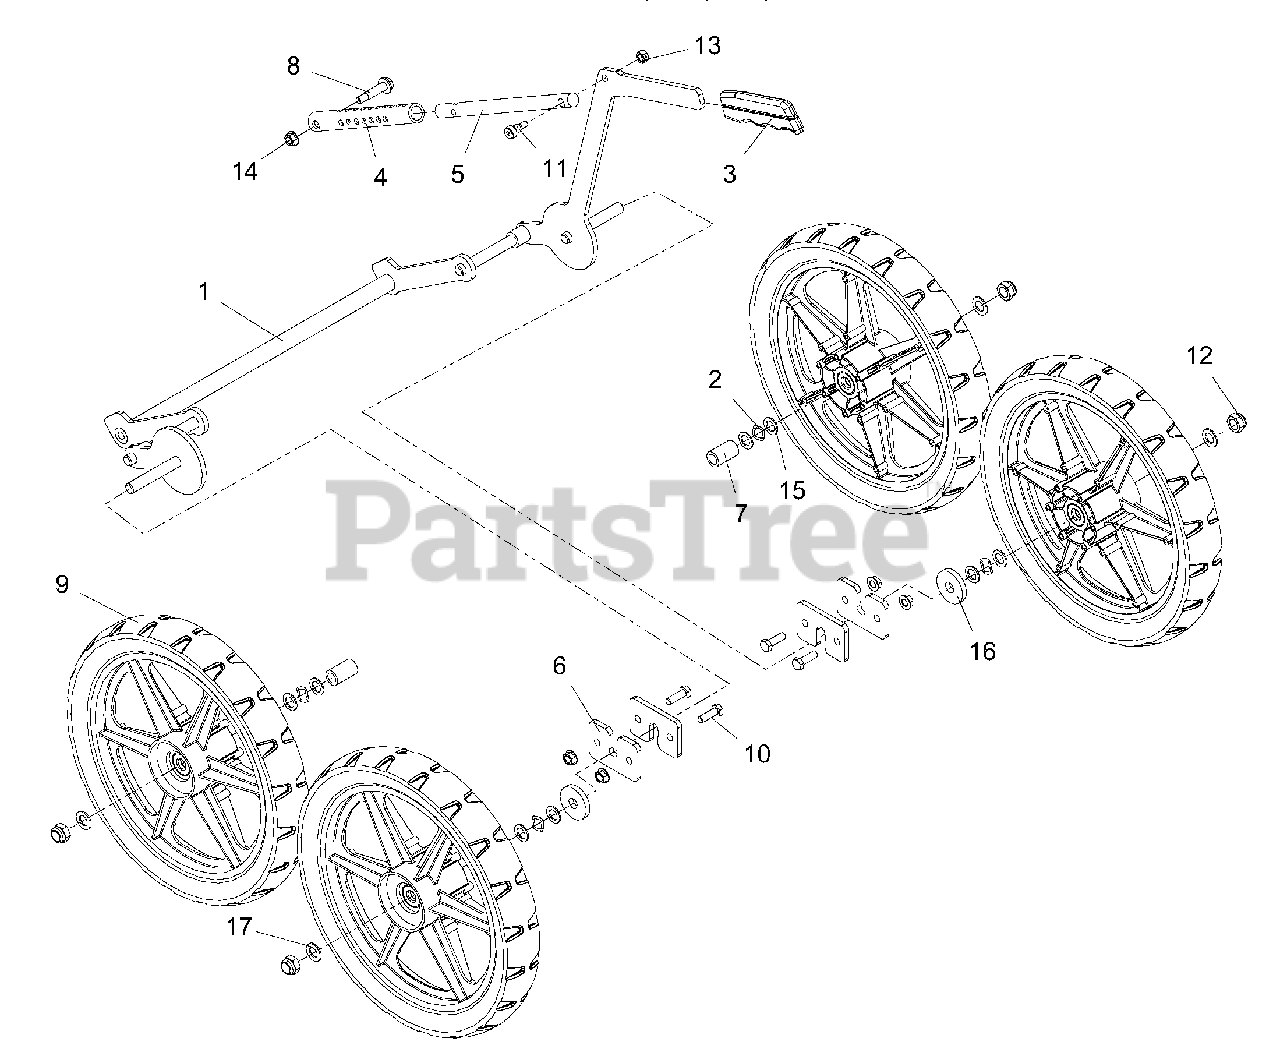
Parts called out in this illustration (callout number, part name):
1	WLDMT, AXLE - APV HEIGHT ADJ SYS
2	WAVE WASHER .531 x .781 x .125 FH
3	GRIP, PARKING BRAKE (YELLOW)
4	TUBE, ADJ - APV HEIGHT ADJ
5	ROD, ADJ - APV HEIGHT ADJ
6	PLATE, RETAINER - APV HEIGHT ADJ
7	SPCR, WHEEL - APV REAR WHEEL
8	BLT, SHLDR .50 x 1.30 x .38-16 GR5
9	WHEEL, 14 x 2 .50ID W/DRIVE HUB
10	BLT-HEX .31-18 x 1.00 GR5 YWZC
11	BLT-SHLDR .375 x .750 x .25-20 ZC
12	NUT, ACORN .500-13 LC YWZC
13	NUT-LK-CTR .31-18 YWZC
14	NUT, LK-TOP-FLG .312-18 YWZC
15	WSHR-FL-STL .520 x .827 x .062 YWZC
16	WSHR-FL-STL .515 x 1.625 x .250 YWZC
17	WSHR-FL-STL .505 x .880 x .072 YWZC
